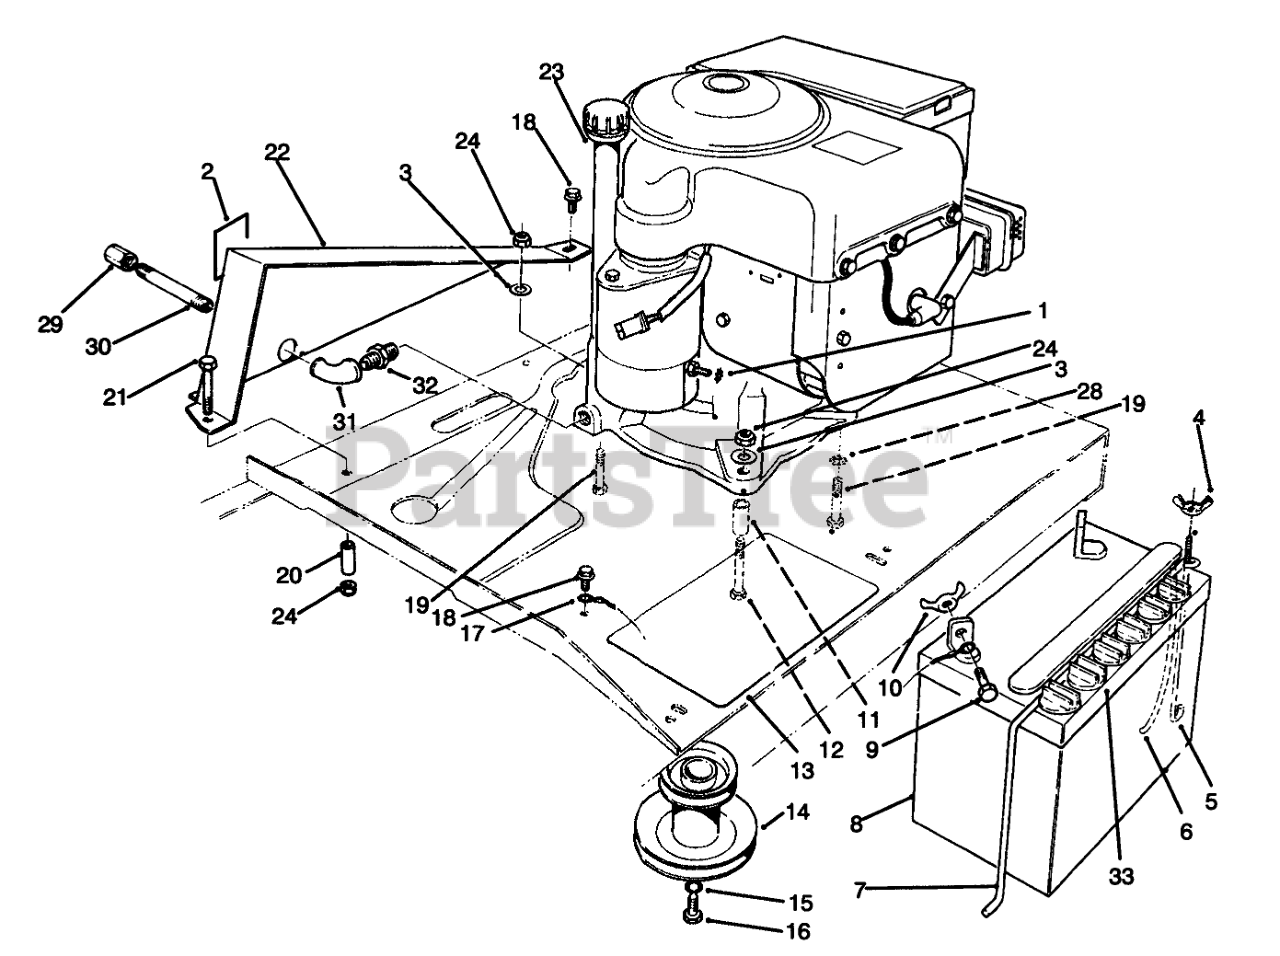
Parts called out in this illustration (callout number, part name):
1	WASHER-LOCK/EXT
2	Decal-Noise
3	WASHER-PLAIN
4	NUT-WING SPECL
5	POST-BATTERY
6	TUBE-BATT DRAIN/80-2600
7	HOLDDOWN-BATTERY
8	Battery
9	SCREW-HH
10	NUT-WING
11	SPACER-PIVOT
12	SCREW-HH
13	PAD-SKID, ANTI
14	Pulley-Engine
15	WASHER-FLAT
16	SCREW-HH
17	WIRE ASM(BATT/GRD.
18	SCREW-HWHTF
19	SCREW-HH
20	GUIDE-BELT
21	SCREW-HH
22	GUIDE-CHAIN
23	Engine-8 H.P. B & S
24	NUT-LOCK, NI
28	WASHER-LOCK
29	CAP-PIPE
30	NIPPLE-PIPE
31	ELBOW-STREET
32	BUSHING-PIPE
33	BATTERY CAP
